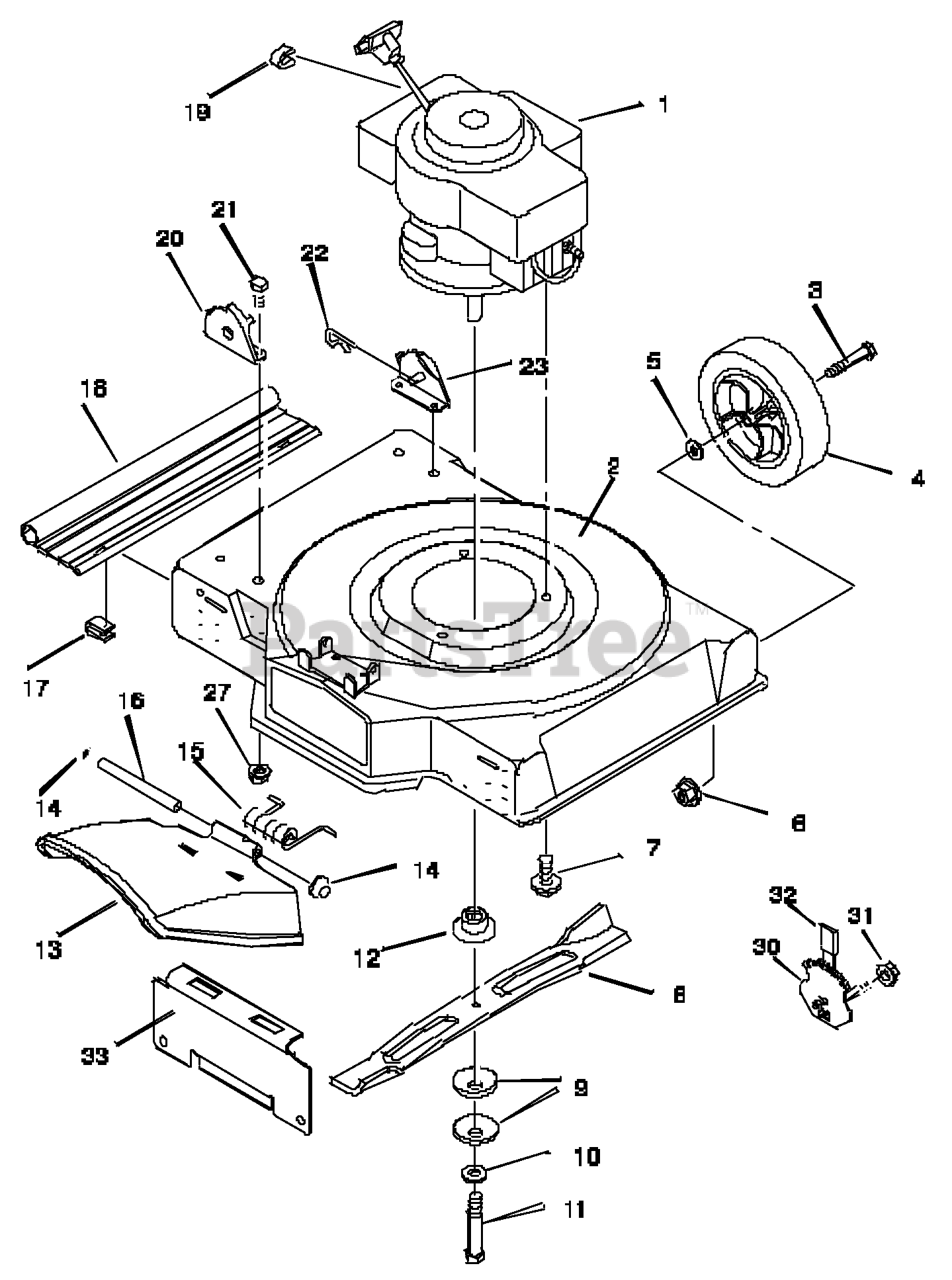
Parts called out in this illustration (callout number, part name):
1	Engine *
2	Housing
3	Bolt, Axle
4	Wheel and Tire *
6	Locknut, Flange
7	Bolt, Engine
9	Washer, Belleville
11	Bolt, Hex
12	Adapter, Blade
13	Deflector, Chute
14	Push- On Cap
16	Pin, Pivot
17	Retainer
18	Deflector, Rear
19	Stop, Rope
20	Bracket, Right Handle
22	Pin, Hair
23	Bracket, Left Handle
27	Nut
30	Adjuster, Height
31	Locknut, Flange
33	Plate, Mulcher
